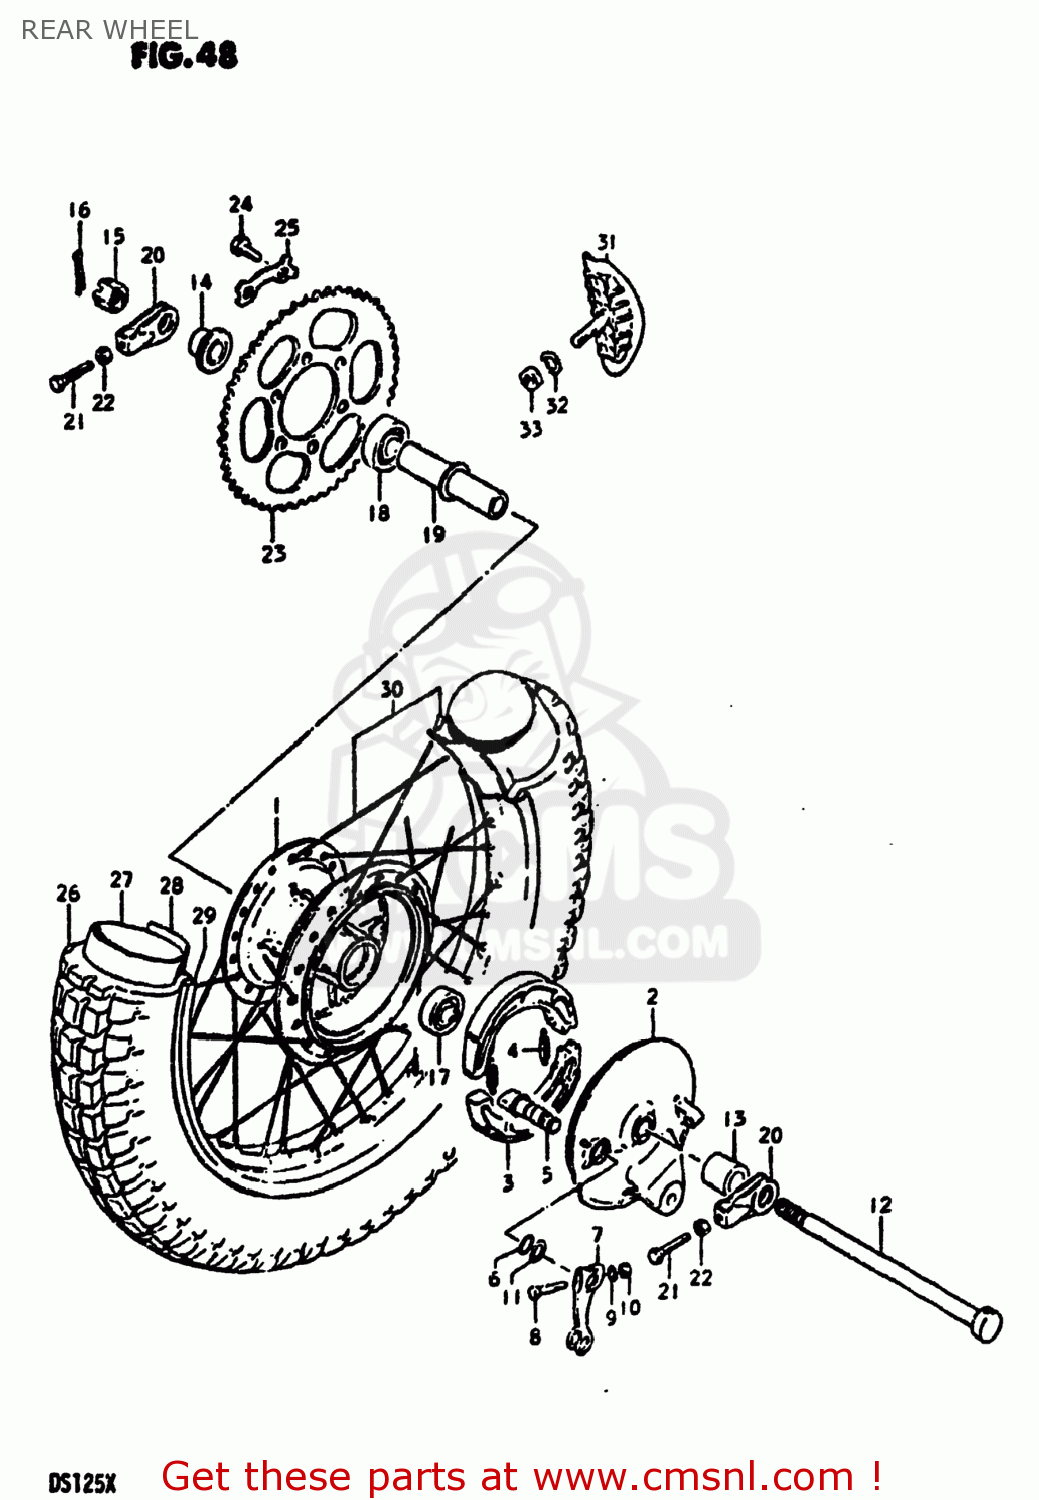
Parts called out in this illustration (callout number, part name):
1	HUB,REAR WHEEL
2	PANEL,RR BRAKE ANCHOR
3	SHOE,BRAKE
4	SPRING(L:34)
5	CAM,FRONT BRAKE
6	O-RING (D:2.4 ID:13.8)
7	LEVER,RR BRAKE CAM
8	BOLT 6X40
9	NUT
10	NUT
11	WASHER (14.5X22X1.6)
12	AXLE,REAR
13	SPACER(15.2X22X26)
14	SPACER,RR AXLE,L
15	NUT
16	COTTER PIN
17	BEARING
18	BEARING
19	SPACER,RR WHEEL HUB BEARING
20	ADJUSTER,CHAIN,R
21	BOLT(8X40)
22	NUT
23	SPROCKET,REAR
24	BOLT(8X30)
25	WASHER
26	TIRE
27	TUBE ASSEMBLY,WHEEL,INNER
28	PROTECTOR,INNER TUBE
29	RIM,REAR WHEEL
30	SPOKE SET
31	STOPPER,BEAD
32	WASHER
33	NUT
